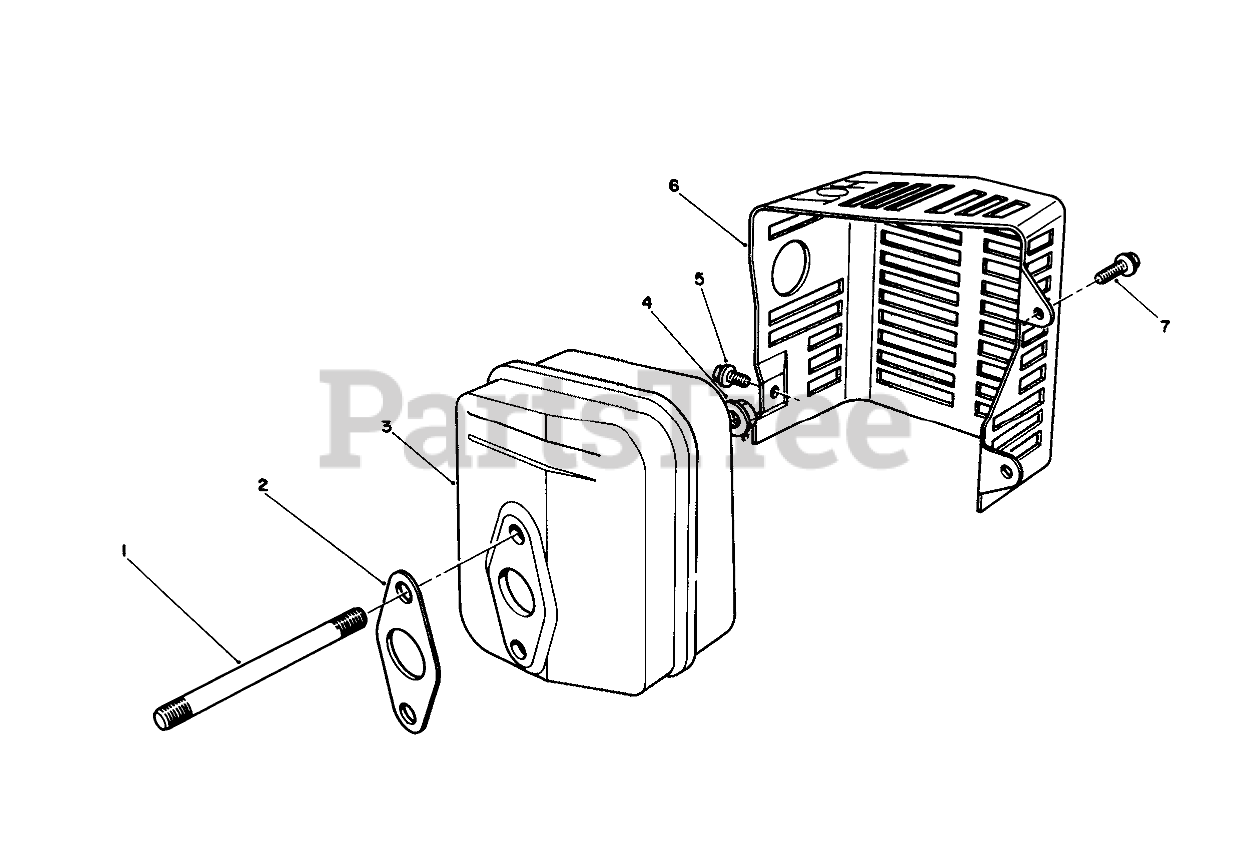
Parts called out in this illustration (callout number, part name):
2	GASKET
3	MUFFLER
5	SCREW
6	COVER
